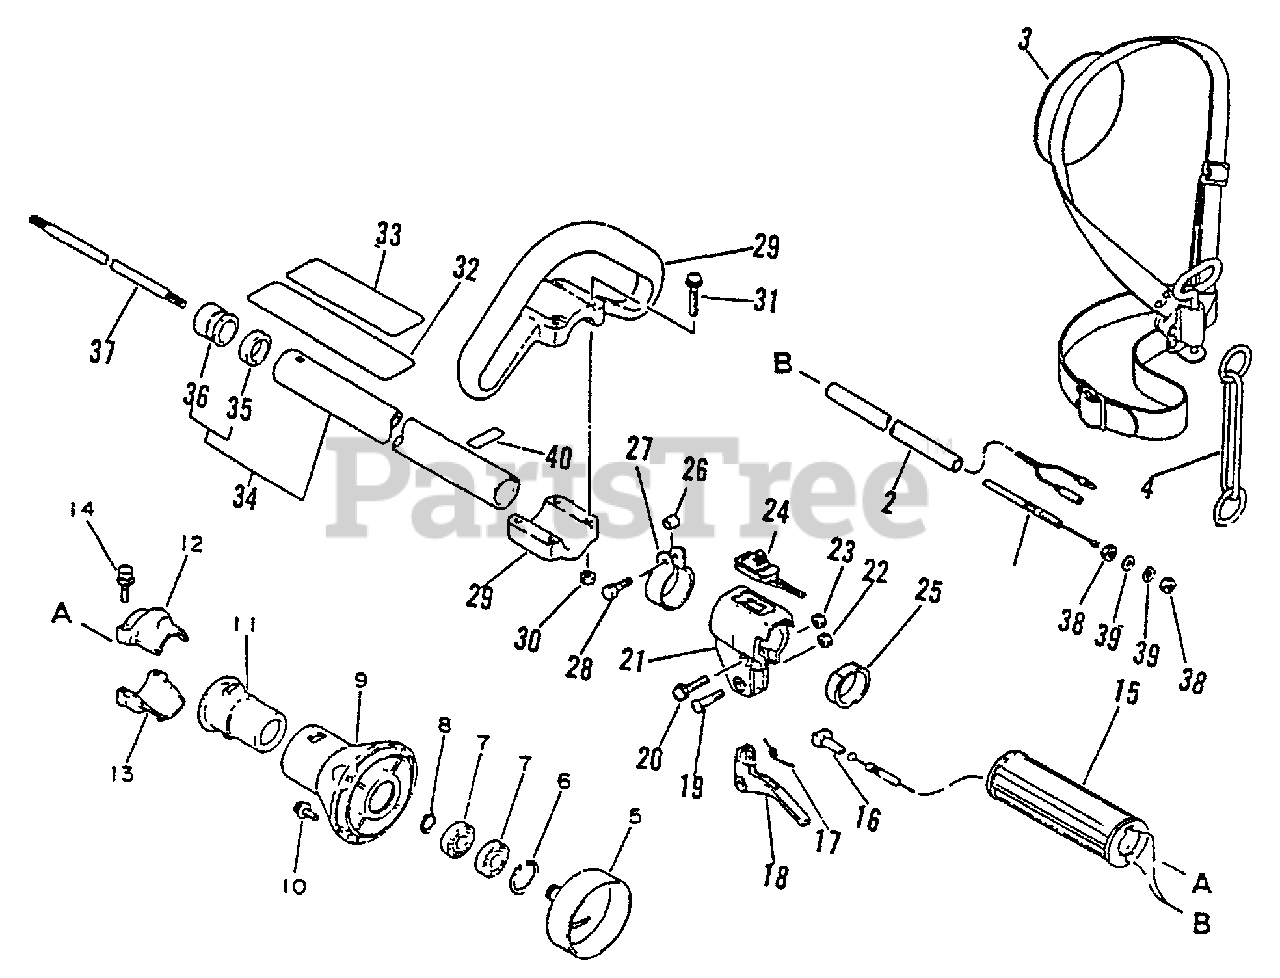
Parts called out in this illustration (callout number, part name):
1	CABLE, THROTTLE
2	TUBE - VINYL
3	SHOULDER STRAP ASSY
5	DRUM, CLUTCH
6	RING, RETAINING - 28
7	BEARING, BALL - 6001
8	RING, RETAINING - 12
9	CASE, CLUTCH
10	SCREW - 5X16
12	CLAMP, MAIN PIPE
13	CLAMP, MAIN PIPE
14	BOLT - 5X25
15	GRIP, HANDLE
16	GUIDE, CABLE
17	SPRING, TRIGGER
18	TRIGGER, THROTTLE
19	SCREW - 5X30
20	SCREW - 5X30
21	BRACKET, THROTTLE CONTROL
22	LOCKNUT - 5
24	IGNITION SWITCH ASSY
25	SPACER
28	BOLT - 5X18
29	LOOP HANDLE ASSY
31	SCREW - 5X35
32	LABEL - CAUTION
33	LABEL - CAUTION
34	MAIN PIPE ASSY
37	DRIVESHAFT - SOLID
39	WASHER - 6
40	LABEL - ALIGNMENT
